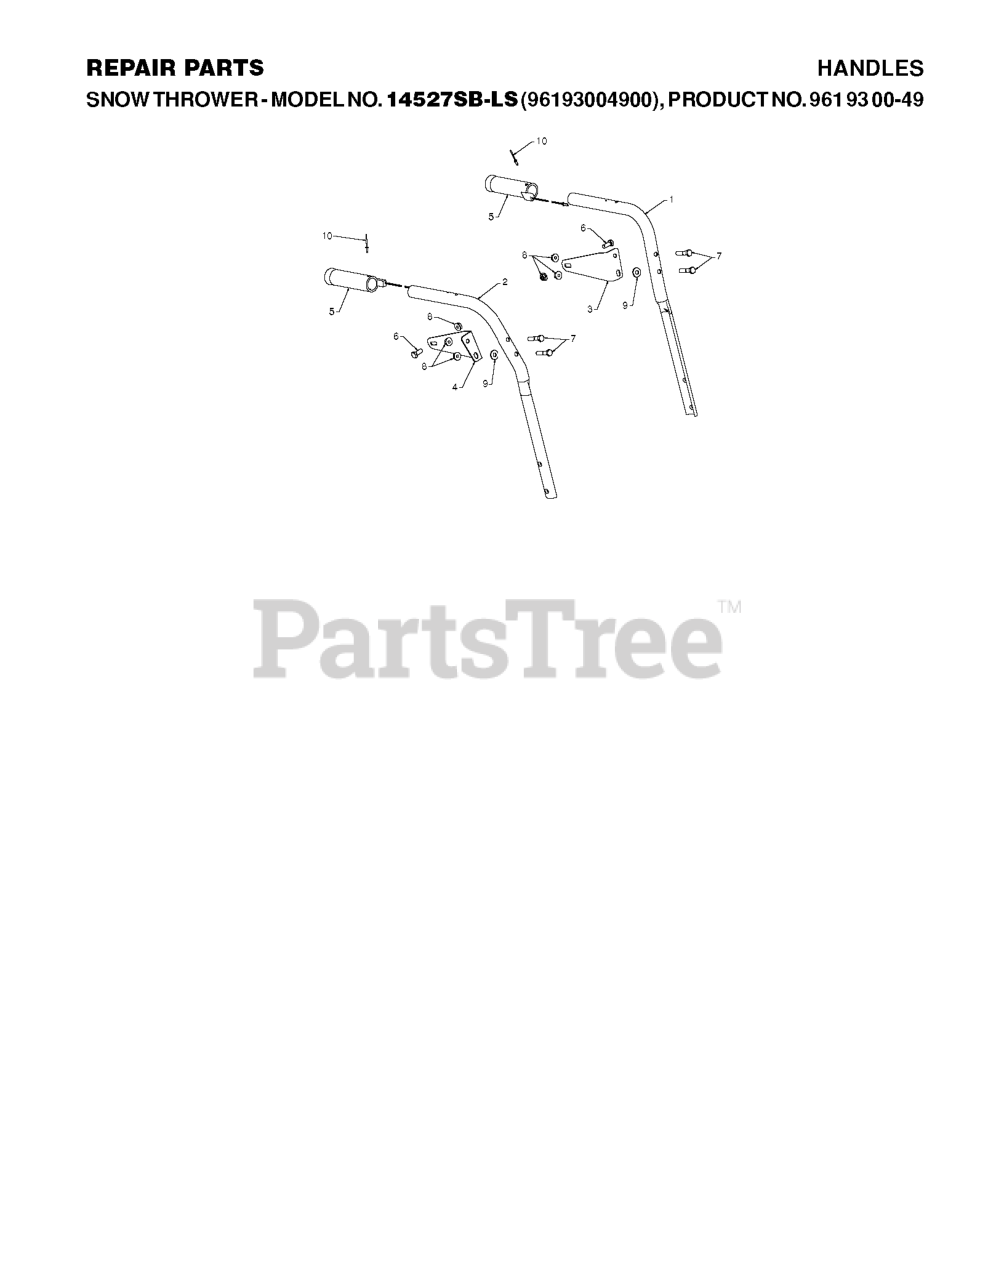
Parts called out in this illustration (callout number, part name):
1	TUBE.HANDLE.PLOW.LH.GREY
2	TUBE.HANDLE.PLOW.RH.GREY
3	BRACKET.PANEL.LH.
4	BRACKET.PANEL.RH.
5	GRIP.HANDLE.HEATED
6	BOLT.FIN.HEX.5/16-18X3/4
7	HEX BOLT
8	NUT.LOCK.5/16-18
9	WASHER.20X8.5
10	RIVET.POP.1/8X
